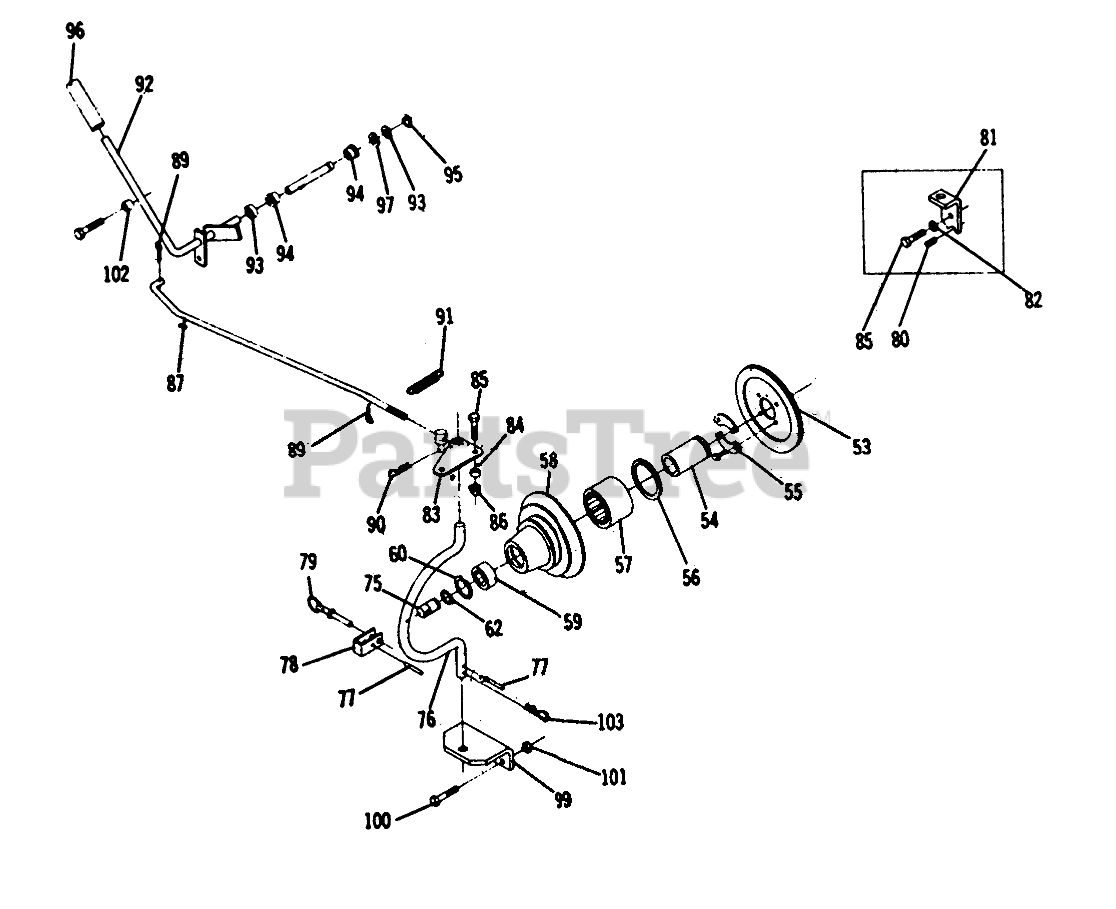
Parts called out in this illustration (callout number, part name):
75	SHAFT-PTO
76	ROD HOUSING (NS)
77	SPIROL PIN
78	Clevis
79	Pin
80	Set Screw 3/8-16 x 3/4
81	Bracket-Engine
82	Lockwasher
83	PLATE R
84	SPACER
85	Bolt 3/8-16 x 1
86	LOCKNUT-FLANGE
87	Clutch Rod
88	TRUNNION
89	Cotter Pin
90	Hairpin
91	Spring
92	Clutch Lever Assy.
93	SPACER
94	BUSHING-FLANGED
95	E Ring
96	GRIP
97	Washer
98	SHIM-WASHER
99	Axle
100	Bolt 3/8-16 x 1
102	Spacer
103	Hairpen
